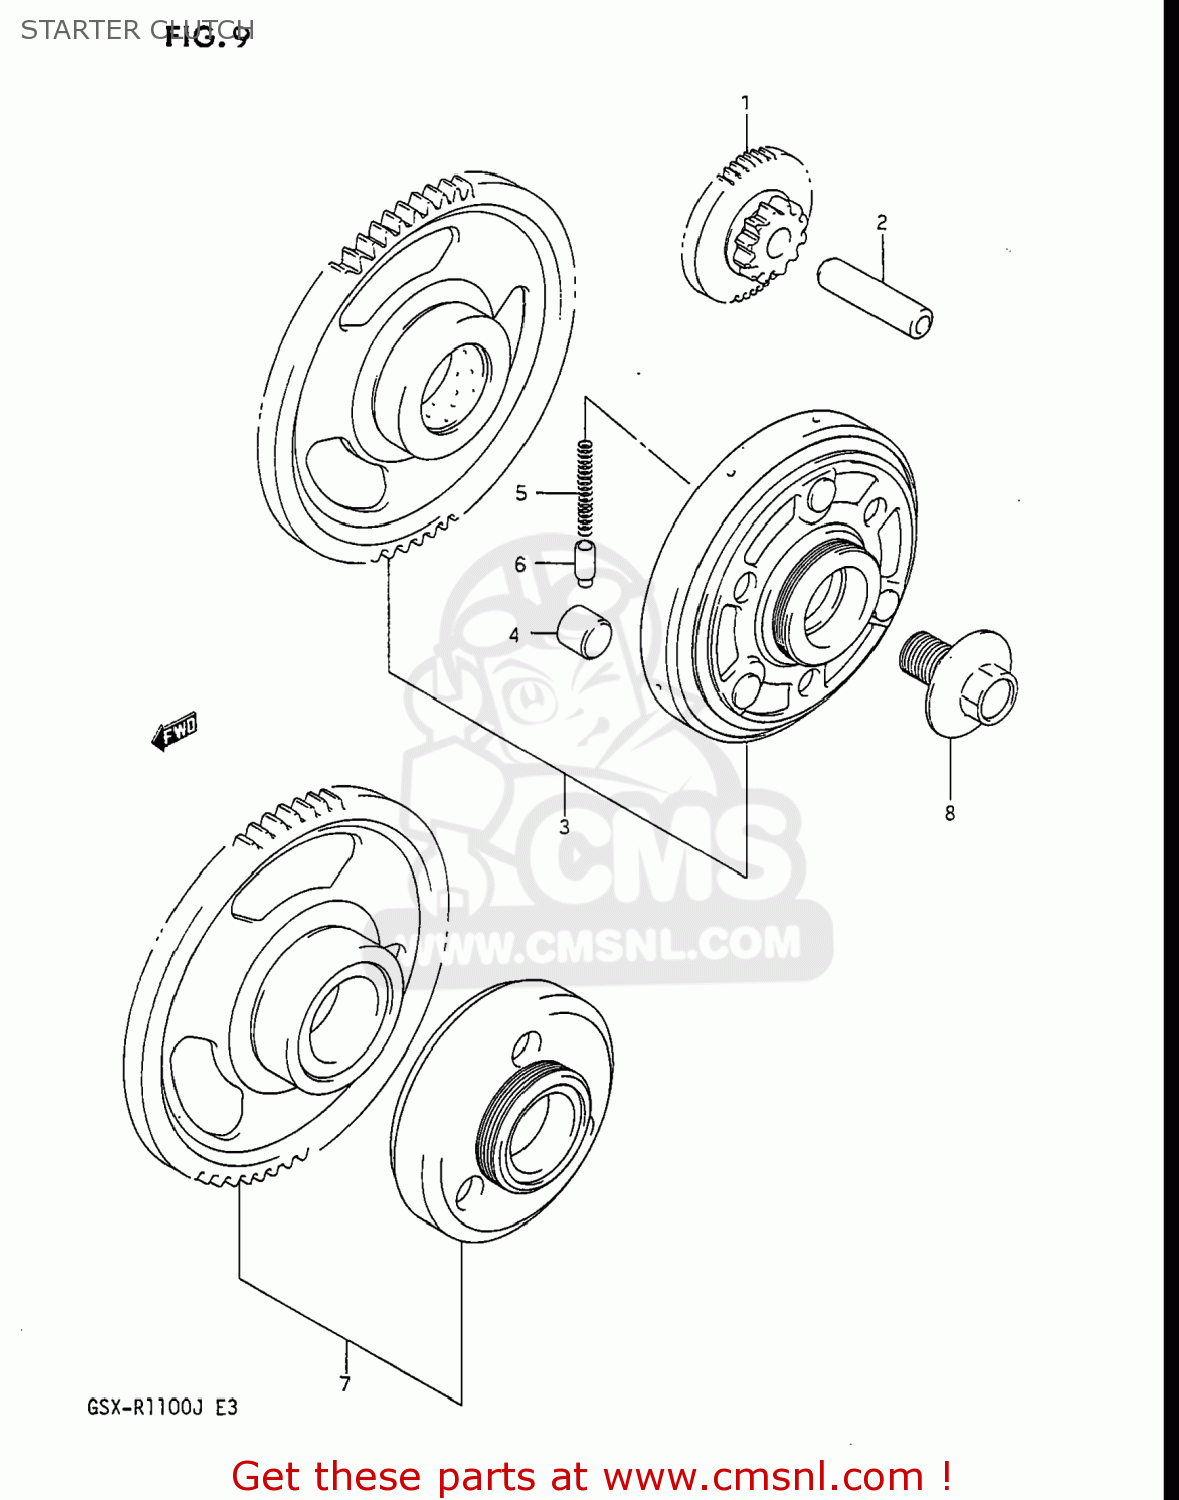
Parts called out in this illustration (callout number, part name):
1	GEAR,STARTER IDLE(NT:12,53)
2	PIN(7X11X42)
3	CLUTCH SET,STARTER
4	ROLLER(15X13)
5	SPRING
6	PIECE,PUSH
7	CLUTCH SET,STARTER
8	BOLT(14X21)
